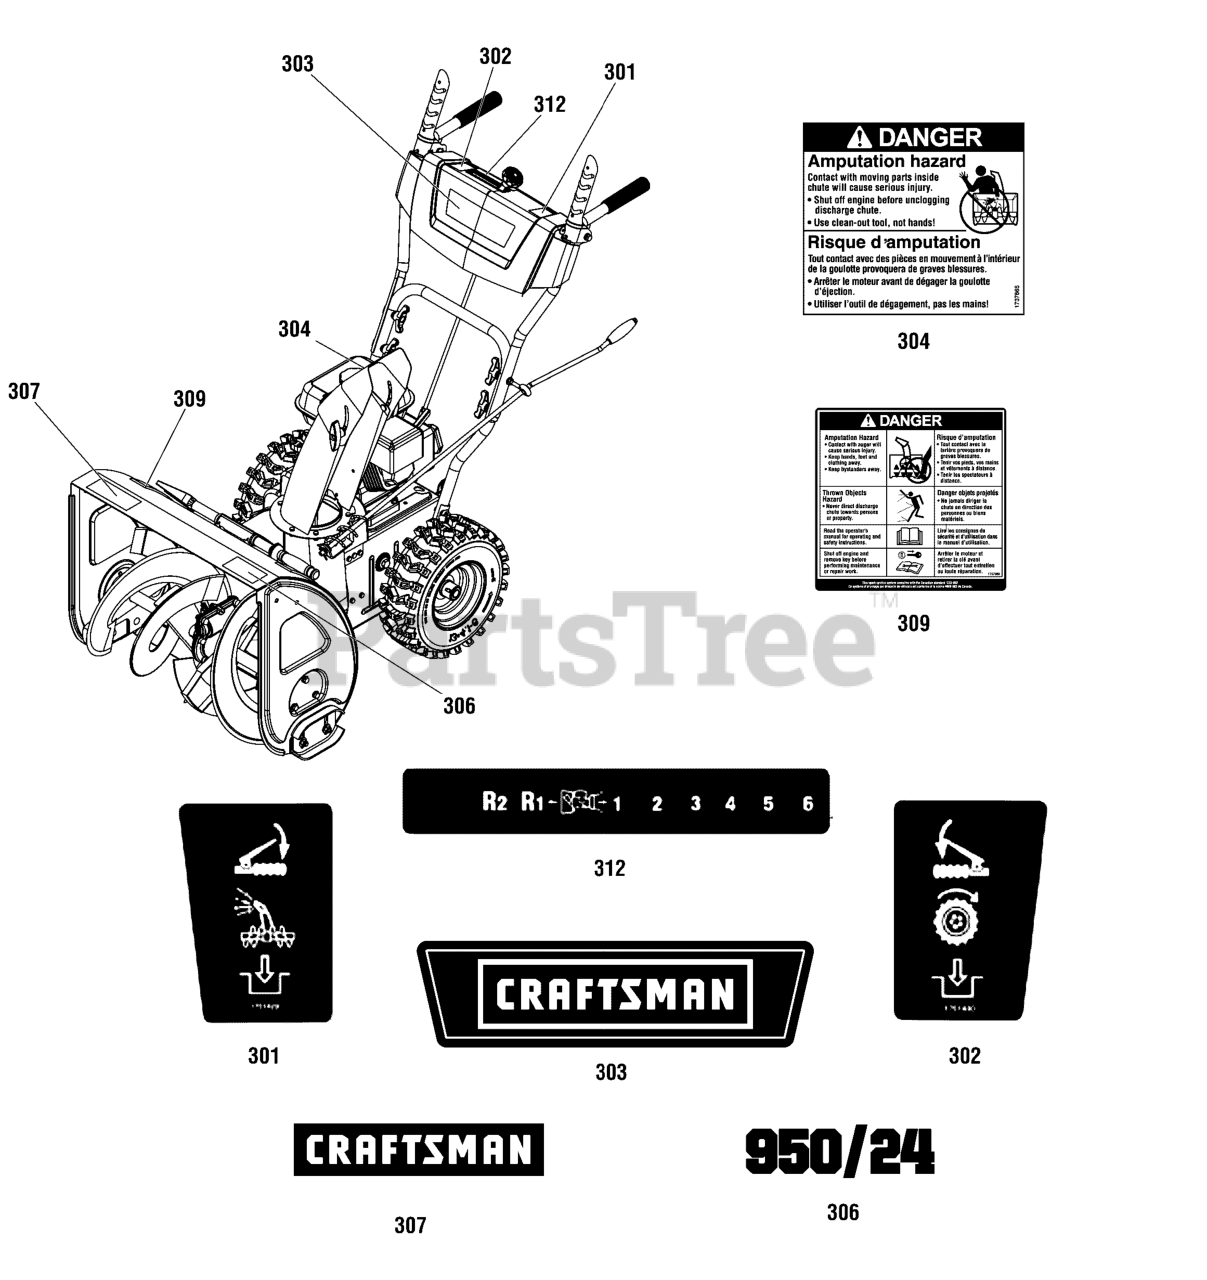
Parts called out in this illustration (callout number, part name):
1	KIT-DECAL, Craftsman, 950/24
301	*DECAL, Auger Control
302	*DECAL, Traction Control
303	*DECAL, Control Panel, Craftsman
304	DECAL, Danger Chute
307	*DECAL, Auger Housing, Craftsman
309	DECAL, Danger Foot
312	*DECAL, 1-6 Transmission Speed Control
